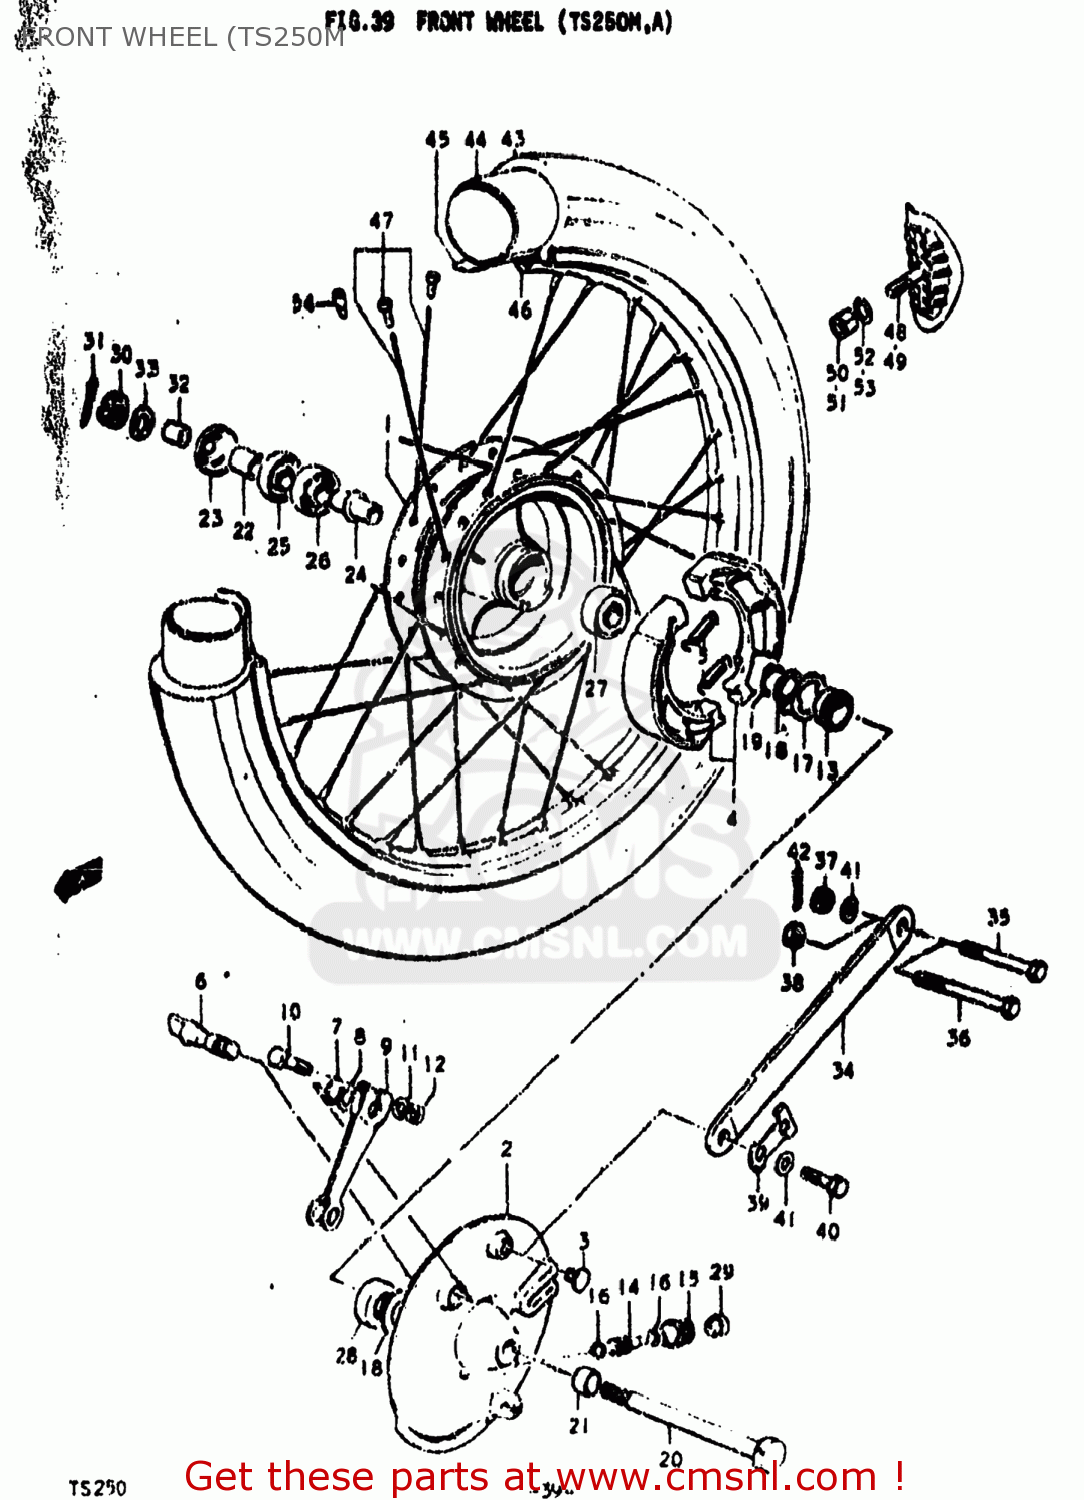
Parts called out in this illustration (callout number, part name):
1	HUB,FRONT
2	PANEL,FRONT HUB
3	CAP(OD:20)
4	SHOE,BRAKE
5	SPRING,BRAKE SHOE
6	CAM,FRONT BRAKE
7	O-RING,BOSS
8	WASHER (15X24X1.6)
9	LEVER,FRONT BRAKE CAM
10	BOLT
11	WASHER
12	NUT
13	GEAR,SPEEDOMETER
14	PINION,SPEEDOMETER
15	BUSHING,SPEEDOMETER PINION
16	WASHER (5.1X9X0.4)
17	DRIVER,SPEEDOMETER GEAR
18	WASHER(22.5X27X1)
19	CIRCLIP
20	AXLE,FRONT
21	SPACER
22	SPACER
23	DUST SEAL,FRONT HUB DRUM
24	SPACER,FRONT HUB BEARING
25	OIL SEAL
26	BEARING
27	BEARING
28	OIL SEAL
29	SEAL,OIL(6X10X3)
30	NUT 12MM
31	COTTER PIN
32	SPACER
33	WASHER
35	BOLT
36	BOLT
37	NUT 8MM
38	NUT
39	MUD FLAP,FRONT FENDER,LEFT
40	BOLT(8X19.5)
41	WASHER
42	PIN
43	TIRE,FRONT
44	TUBE
45	PROTECTOR,WHEEL,INNER
46	RIM,FRONT WHEEL
47	SPOKE SET,FRONT
48	STOPPER,BEAD
49	STOPPER,BEAD
50	NUT
51	NUT
52	WASHER
53	WASHER
54	BALANCER,WHEEL (50G)
